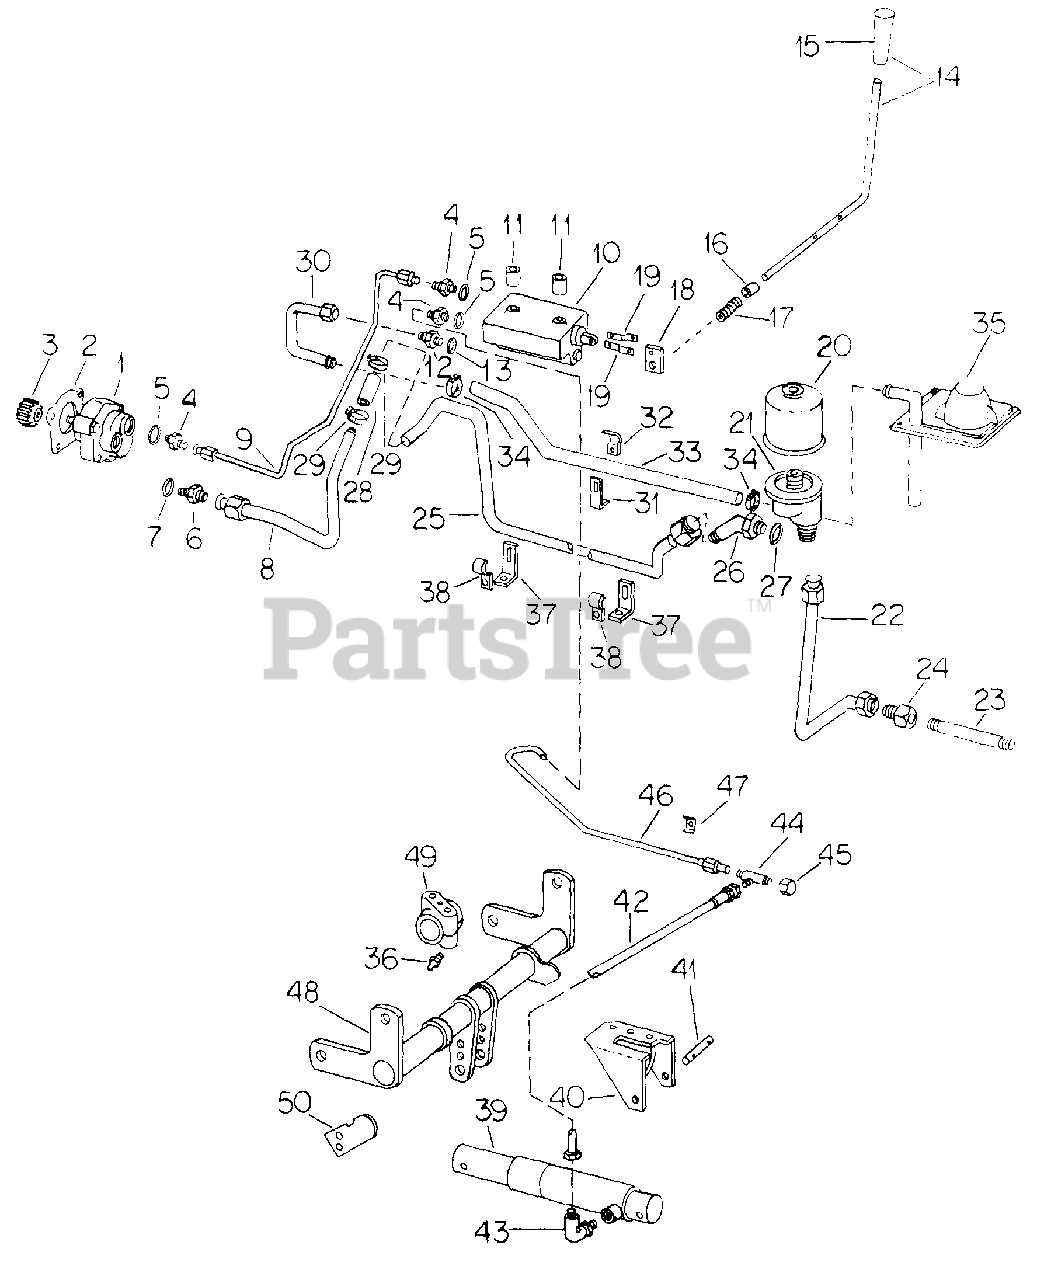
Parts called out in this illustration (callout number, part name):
1	PUMP ASSY, HYD - CESSNA
2	GASKET, PUMP
3	GEAR, PUMP DRIVE - 10T
4	CONNECTOR, 9/16-18 37 DEG HYD FLARED TUBE SHORT SWIVEL
5	O-RING, 3/8 OD TUBE
6	CONNECTOR, 7/8-14 HYD 37 DEG FLARED TUBE SHORT REDUCER
7	O-RING, 5/8 OD TUBE
8	TUBE ASSY, SUCTION SHORT
9	TUBE ASSY, PRESSURE LONG
10	VALVE ASSY, CONTROL
11	SPACER
12	CONNECTOR, 3/4-16 37 DEG HYD FLARED TUBE SHORT SWIVEL
13	O-RING, 1/2 OD TUBE
15	GRIP, HANDLE
16	SPACER, HANDLE
17	SPRING, VALVE HANDLE
18	LEVER, VALVE HANDLE
19	BAR, HYD VALVE OPERATING
20	FILTER ASSY, HYD OIL-SPIN-ON
21	BASE, HYD OIL FILTER
22	TUBE ASSY, HYD FILTER SUCTION
23	NIPPLE, 1/2 X 6-1/2 LONG PIPE
24	CONNECTOR, HYD FLARED TUBE
25	TUBE ASSY, SUCTION LONG
26	ELBOW, 1-1/16-12 37 DEG FLARED TUBE 45 DEG ADJ
27	O-RING, 3/4 OD TUBE
28	HOSE, SUCTION TUBE
30	TUBE ASSY, RETURN
31	SUPPORT, TUBE CLAMP
32	CLAMP, HYD HOSE
33	HOSE, RETURN
35	HOUSING ASSY, GEAR SHIFT LEVER
36	FITTING, 3/16 65 DEG ANGLE DRIVE TYPE LUB
37	SUPPORT, TUBE CLAMP
38	CLAMP, HYD HOSE
39	CYLINDER ASSY, HYD 1-3/4 X 5 SINGLE ACTING
40	BRACKET ASSY, CYL MTG
41	PIN, LIFT CYLINDER
42	HOSE, HYD
43	ELBOW, 9/16-18 37 DEG FLARED ADJ 90 DEG
44	TEE, 9/16-18 37 DEG HYD FLARED TUBE THREE WAY
45	CAP, 9/16-18 37 DEG HYD FLARED TUBE
46	TUBE ASSY, HYD CYL
47	CLAMP, HYD TUBES
48	ROCKSHAFT ASSY
49	BEARING ASSY, ROCKSHAFT
50	BAR, ROCKSHAFT STOP
